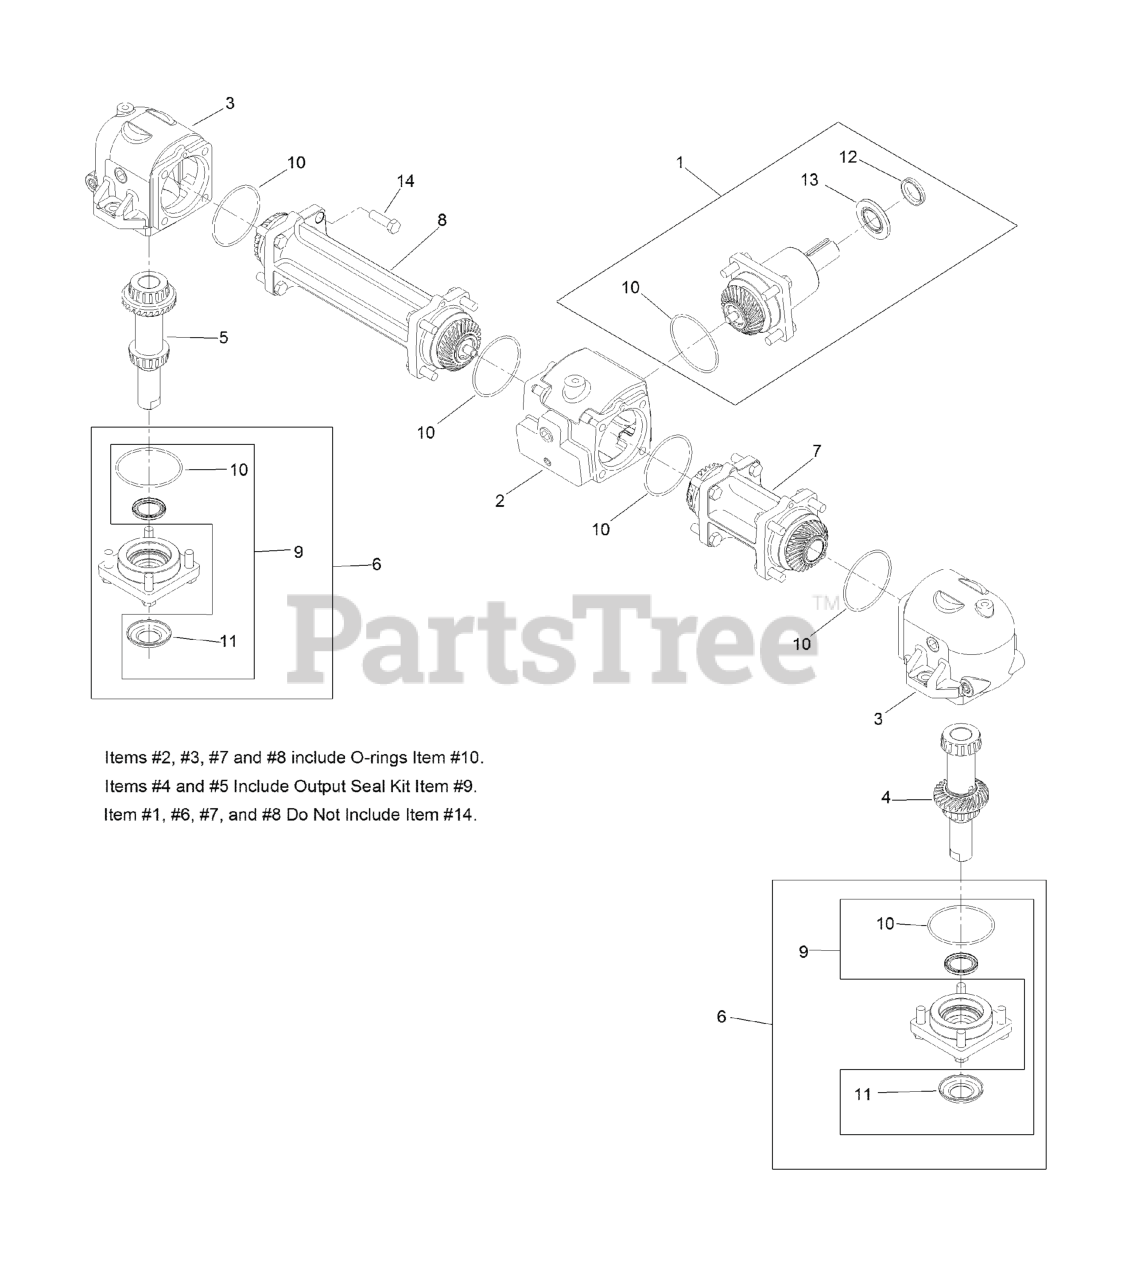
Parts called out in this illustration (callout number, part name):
1	INPUT PINION ASM
2	HOUSING-CENTER
3	HOUSING-END
4	LH OUTPUT SHAFT AND GEAR
5	RH OUTPUT SHAFT AND GEAR
6	CAP-OUTPUT
7	TUBE-CONNECTOR, SHORT
8	TUBE-CONNECTOR, LONG
9	OUTPUT SEAL KIT
10	SEAL-O-RING
11	WASHER-CUPPED
12	SEAL-V-RING
13	SEAL-INPUT
